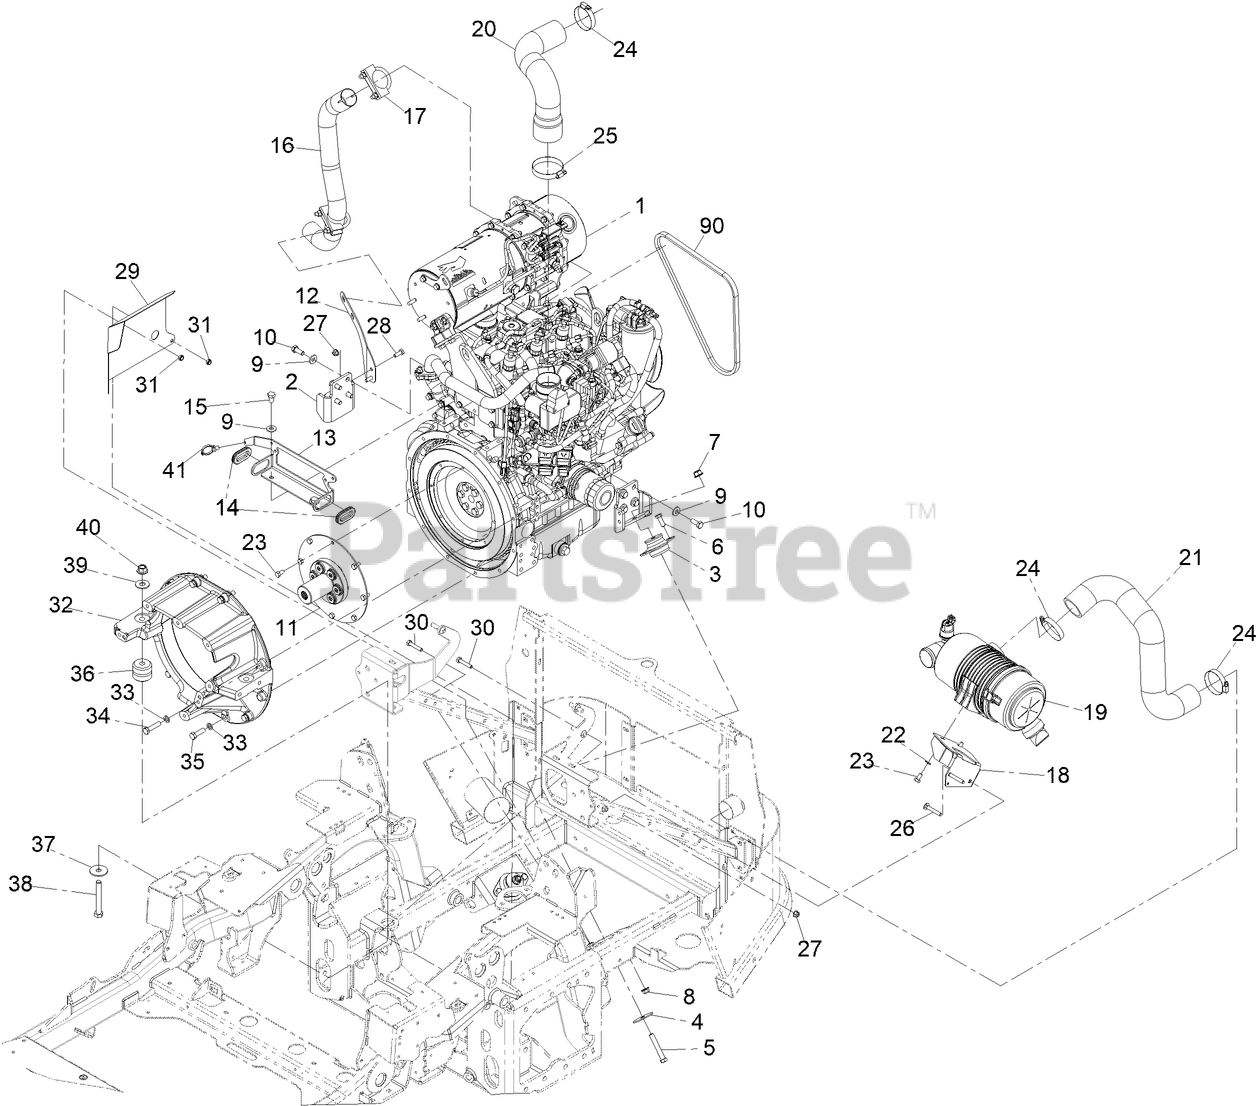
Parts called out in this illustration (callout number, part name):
1	ENGINE-YANMAR, 3TNV88C-DTR5
2	MOUNT-MOTOR, UPPER
3	MOUNT- ISOLATOR, ENGINE
4	WASHER-SNUBBING
5	SCREW-HH
6	SCREW-HH
7	NUT-HF, NI
8	NUT-HF, NI
9	WASHER-BELLEVILLE
10	SCREW-HH
11	COUPLING-FLYWHEEL
12	BRACKET-MOUNT
13	PLATE_GUIDE BRACKET
14	GROMMET-RUBBER
15	SCREW-HH
16	TUBE-EXHAUST
17	CLAMP
18	BRACKET-CLEANER, AIR
19	ASM, HDAC
20	HOSE-AIR
21	HOSE-AIR
22	WASHER-BELLEVILLE
23	BOLT
24	CLAMP-HOSE
25	CLAMP-HOSE
26	BOLT-CARR
27	NUT-HF, NI
28	SCREW-HH
29	DEFLECTOR-AIR
30	SCREW-HH
31	NUT-LOCK, NI
32	HOUSING-FLYWHEEL
33	WASHER-LOCK
34	SCREW-HH
35	SCREW-HH
36	MOUNT-ISOLATOR
37	WASHER-THRUST
38	SCREW-HH
39	WASHER-FLAT
40	NUT-LOCK
41	CLIP-TIE
90	V-BELT
